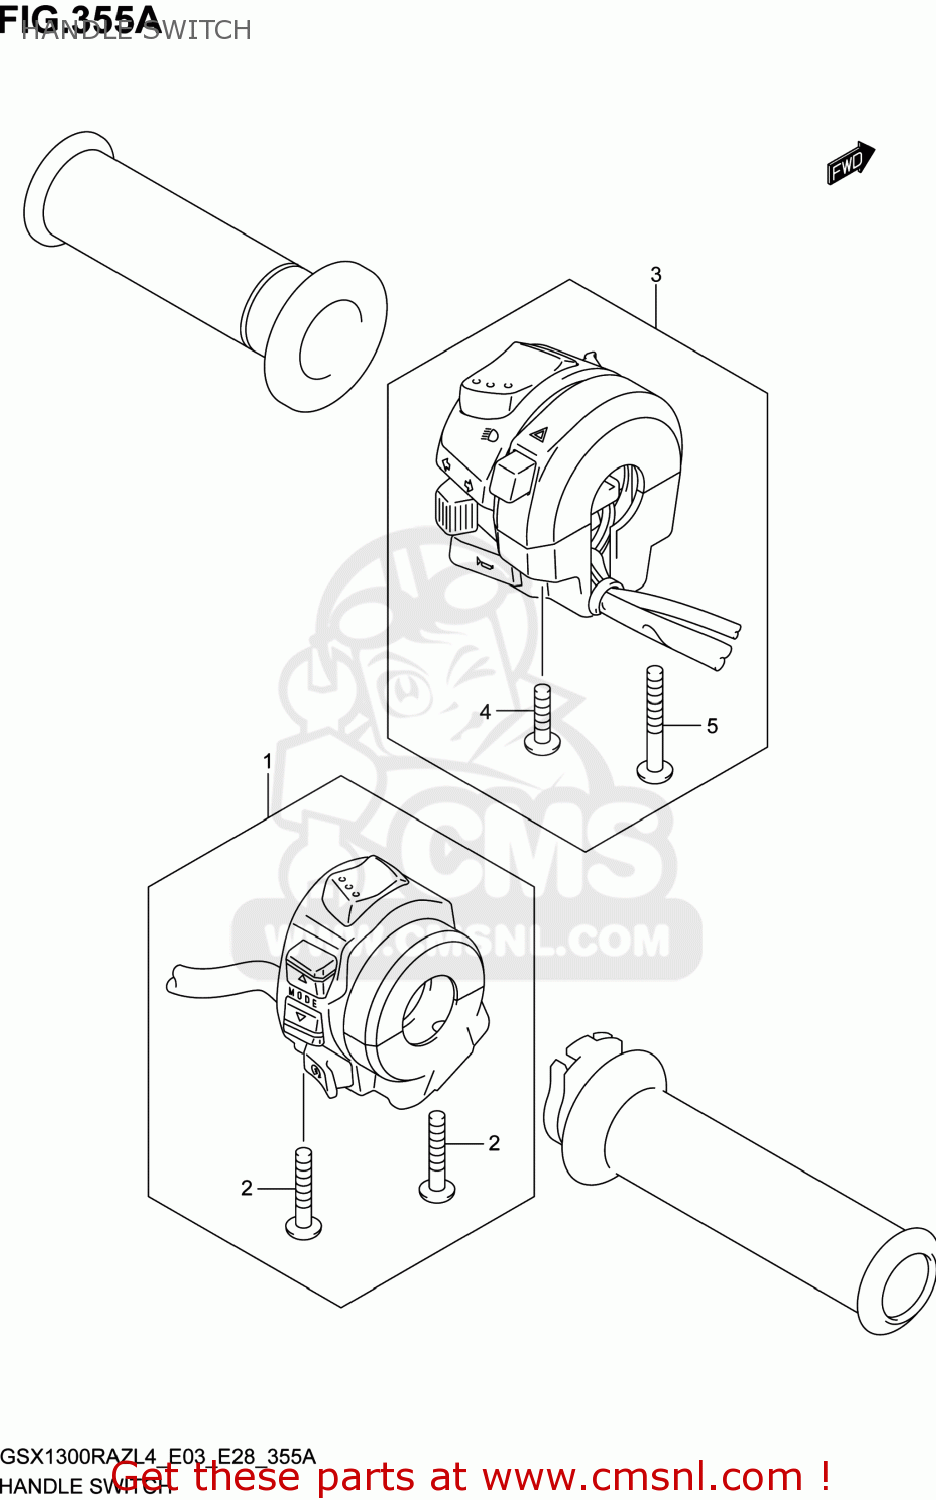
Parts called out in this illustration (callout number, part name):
1	SWITCH ASSY,HANDLE,R
2	SCREW
3	SWITCH ASSY,HANDLE,L
4	SCREW
5	SCREW
